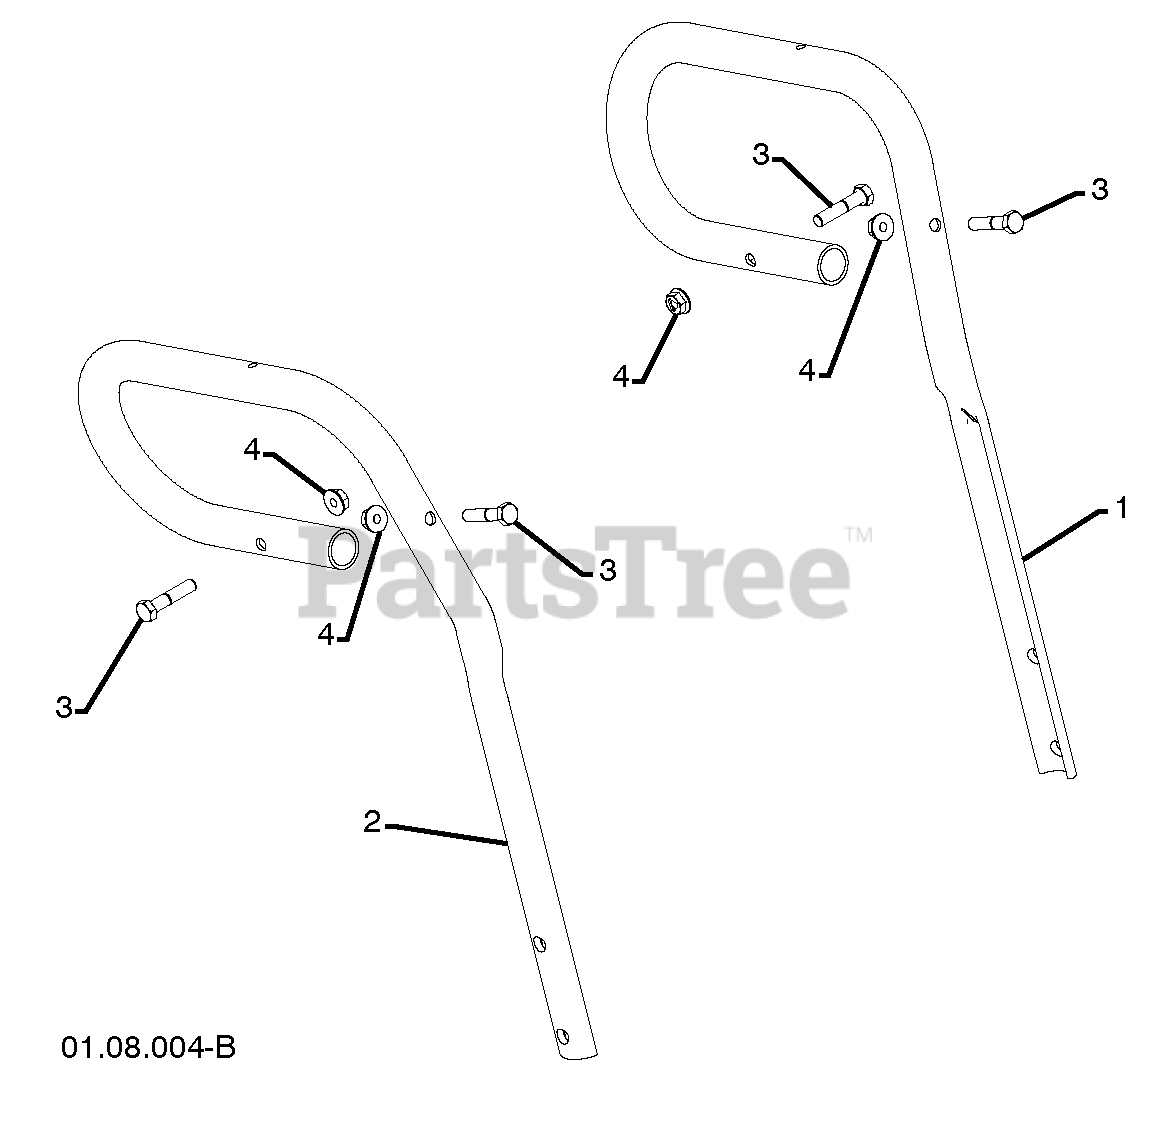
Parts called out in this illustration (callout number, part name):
1	LOOP HANDLE LH
2	LOOP HANDLE RH
3	SCREW 5/16-18 X 1.50
4	NUT 5/16-18
